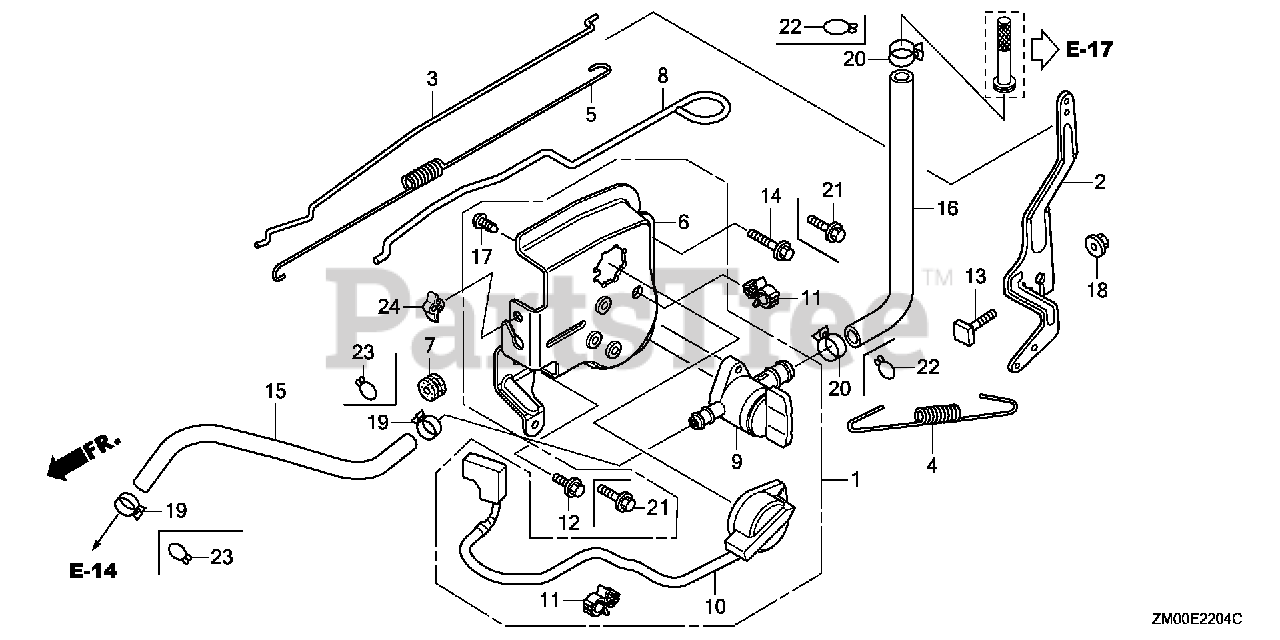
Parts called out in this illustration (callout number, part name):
1	CONTROL ASSY.
2	ARM, GOVERNOR
3	ROD, GOVERNOR
4	SPRING, GOVERNOR
5	SPRING, THROTTLE RETURN
6	BASE, CONTROL
7	GROMMET, CHOKE ROD
8	ROD, CHOKE
9	PETCOCK ASSY.
10	SWITCH ASSY., ENGINE STOP
11	HOLDER, WIRE (FASTEX)
12	BOLT, FLANGE (6X12) (CT200)
13	BOLT, GOVERNOR ARM
14	BOLT, FLANGE (6X32) (CT200)
15	TUBE, FUEL (4.5X140)
15	TUBE, FUEL (4.5X140) (FKM)
16	TUBE, FUEL (7.3X145)
16	TUBE, FUEL (7.3X145) (FKM)
17	SCREW, TAPPING (5X12) (PO)
18	NUT, FLANGE (6MM)
19	CLAMP, TUBE (D8)
20	CLAMP, TUBE (D12)
22	CLIP, TUBE (B12.5)
23	CLIP, TUBE (C9)
